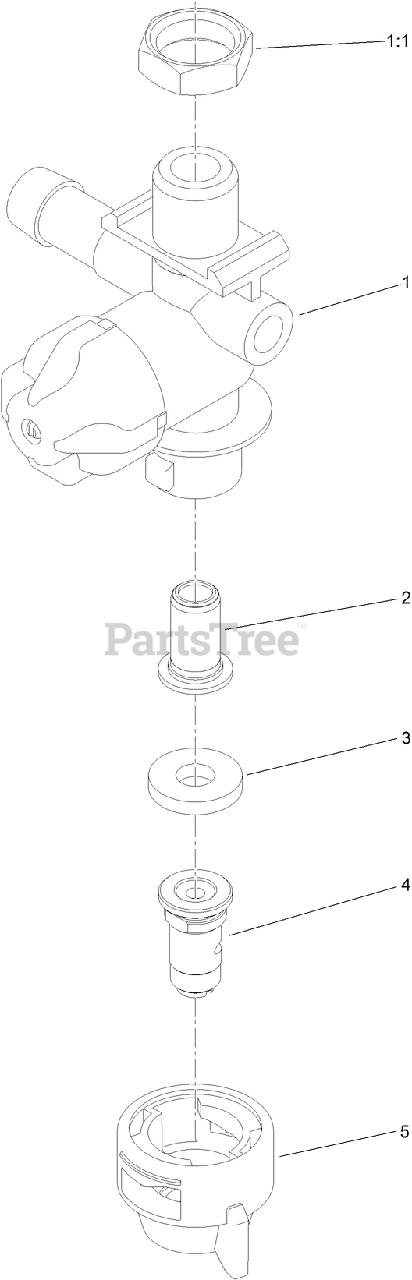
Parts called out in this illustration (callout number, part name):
1	RH NOZZLE BODY ASM
1:1	NUT-NYLON
2	STRAINER-TIP
3	GASKET-SEAL
4	NOZZLE-SPRAY, WHITE
5	CAP-NOZZLE
